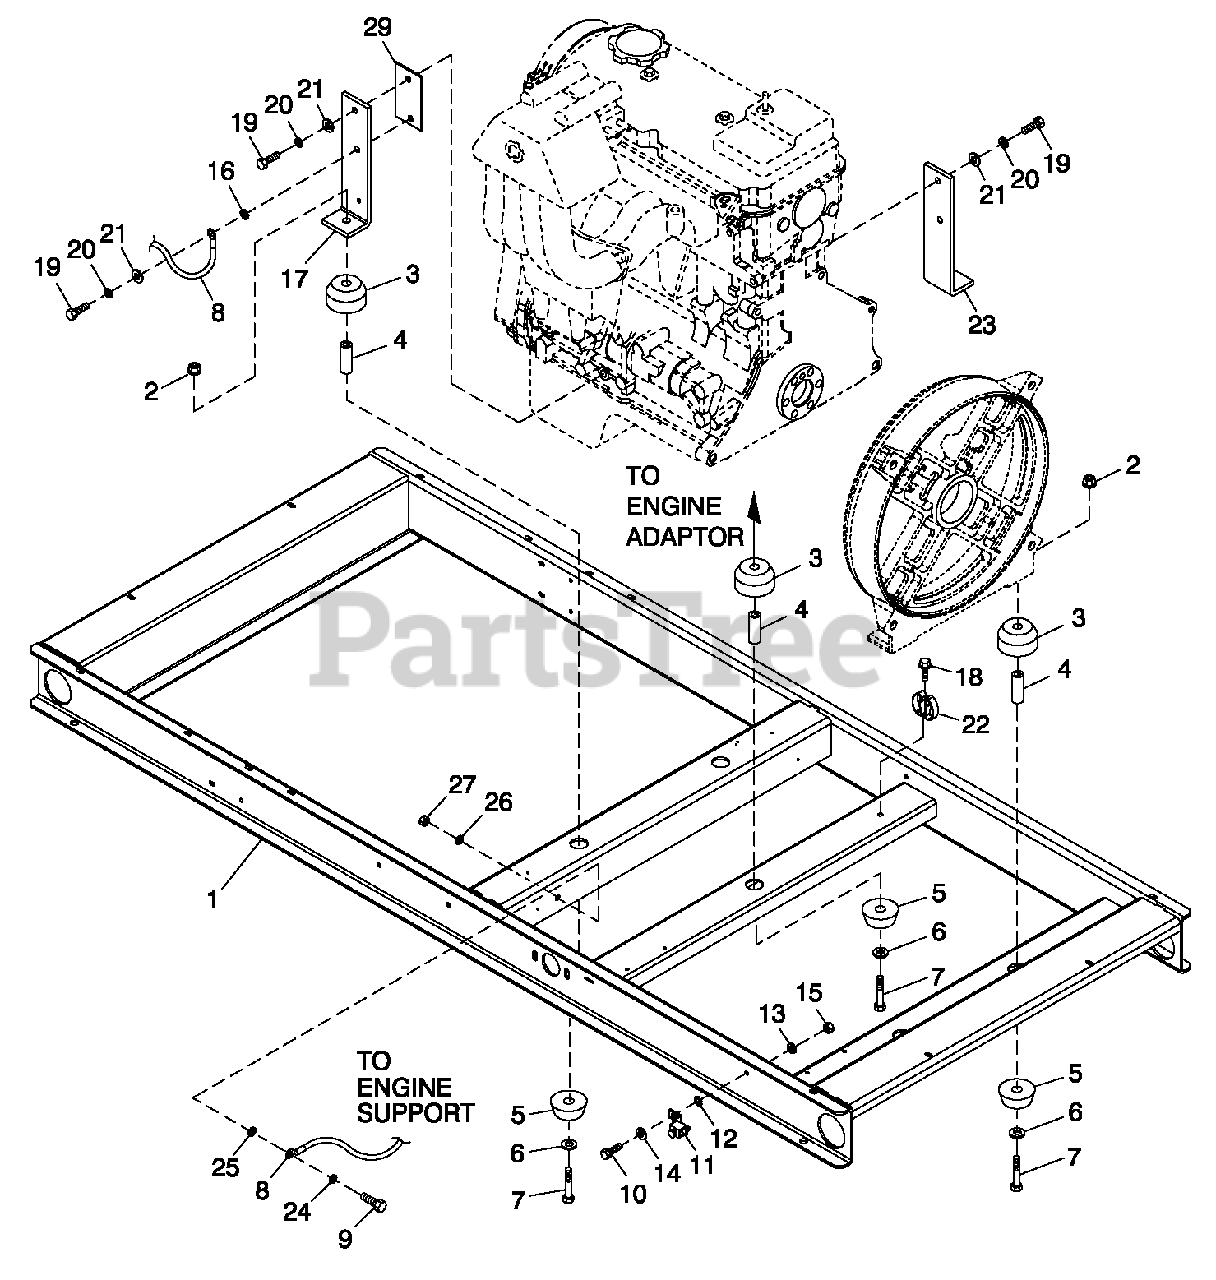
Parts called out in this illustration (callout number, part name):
1	WELDMENT FRAME 2.4L C2
2	NUT FLANGED HEX M12-1.75
3	DAMPENER VIBRATION 40 BLUE
4	SPACER .49 X .62 X 1.87 PWDR/ZNC
5	DAMPENER VIBRATION
6	WASHER FLAT M12
7	SCREW HHC M12-1.75 X 80 G8.8
8	ASSY WIRE 14.00"
9	SCREW HHC M8-1.25 X 30 G8.8
10	SCREW HHC M6-1.0 X 16 G8.8
11	LUG SLDLSS #2-#8 X 17/64 CU
12	WASHER SHAKEPROOF INT 1/4
13	WASHER LOCK M6-1/4
14	WASHER FLAT M6-1/4 ZINC
15	NUT HEX M6 -1.0 G8 YEL CHR
16	WASHER SHAKEPROOF INT 3/8
17	SUPPORT LH ENGINE 2.4L
18	SCREW HHTT M4-0.7 X 8 BP
19	SCREW HHC M10-1.25 X 30 G8.8
20	WASHER LOCK 7/16
21	WASHER FLAT 3/8-M10 ZINC
22	SPRING CLIP HOLDER .37-.62
23	SUPPORT RH ENGINE 2.4L
24	WASHER LOCK M8-5/16
25	WASHER SHAKEPROOF INT 5/16
26	WASHER FLAT 5/16-M8 ZINC
27	NUT HEX M8-1.25 G8 CLEAR ZINC
29	SPACER ENGINE MOUNT (2.4L G1)
